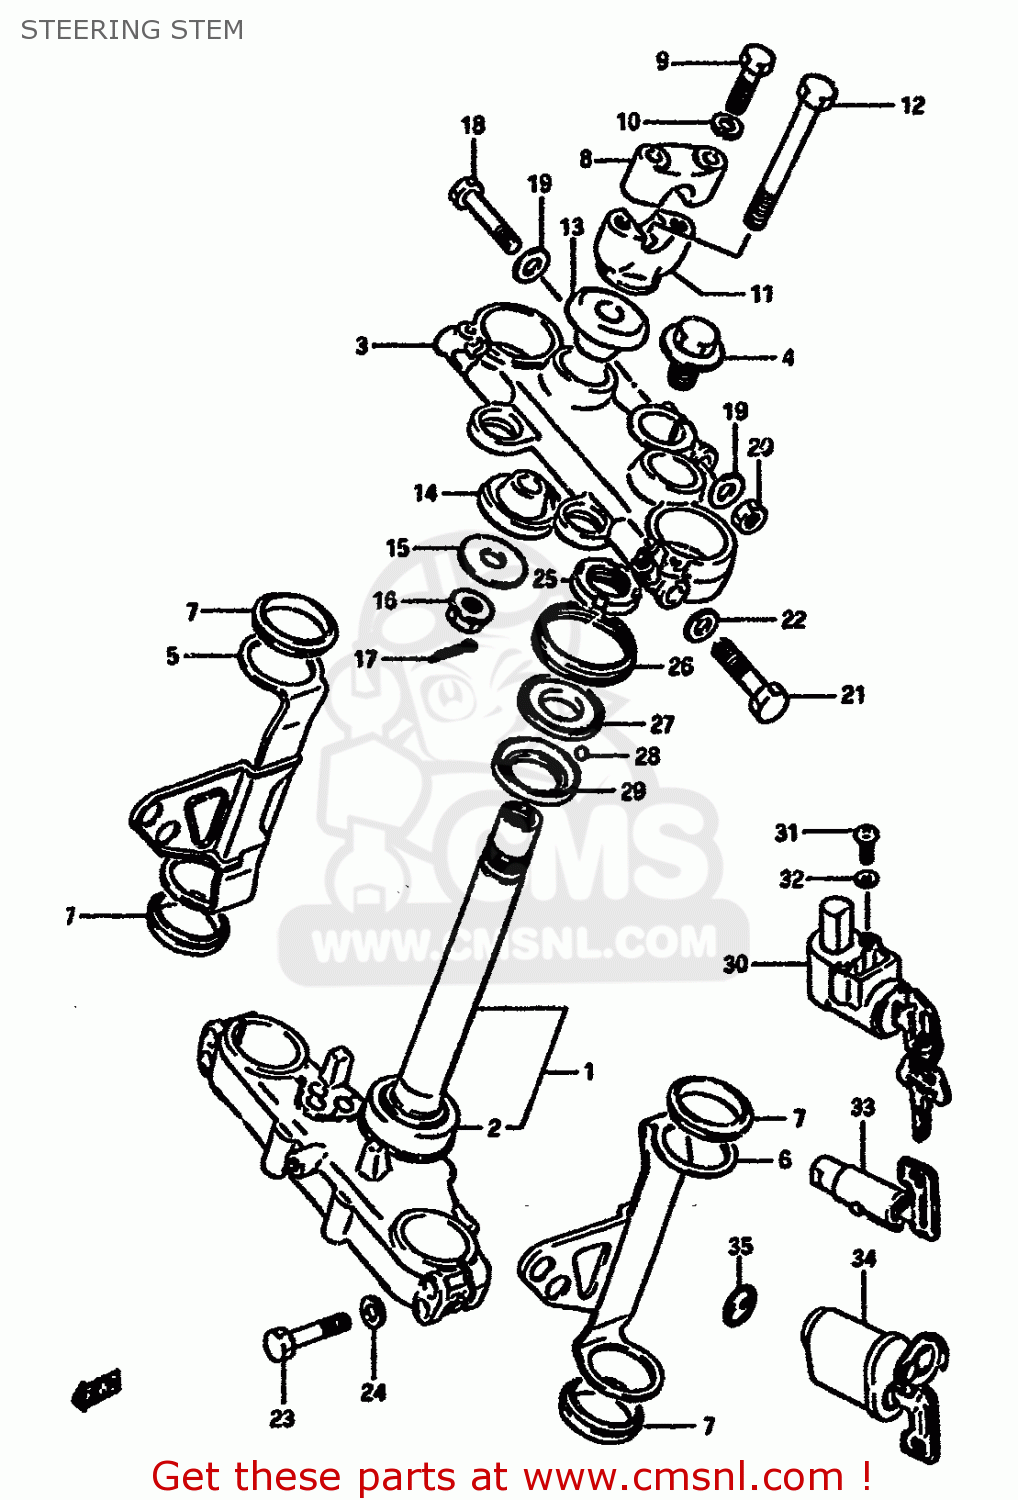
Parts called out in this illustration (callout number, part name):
1	STEM,STEERING
2	BEARING
3	HEAD,STEERING STEM
4	BOLT,STEERING STEM
5	COVER,FORK,RIGHT
6	BRACKET,HEADLAMP,LEFT
7	CUSHION,HEAD LAMP BRACKET
8	HOLDER,HANDLEBAR
9	BOLT
10	LOCK WASHER
11	HOLDER,HANDLE LWR
12	BOLT,HANDLE HOLDER
13	DAMPER,UPR
14	DAMPER,LWR
15	WASHER,HANDLEBAR HOLDER
16	NUT
17	COTTER PIN
18	BOLT
19	WASHER
20	NUT ,8MM
21	BOLT
22	LOCK WASHER
23	BOLT
24	LOCK WASHER
25	NUT,STEERING STEM
26	SEAL,STEERING UPR DUST
27	RACE,STEERING,OUTER,UPPER
28	BALL
29	RACE,STEERING INNER (SUJ)
30	LOCK ASSY,STEERING
31	SCREW
32	LOCK WASHER
33	LOCK ASSY,STEERING(NEIMAN)
34	LOCK ASSY, STEERING (NEIMAN TYPE EXECUTE
35	LABEL,STEERING LOCK
